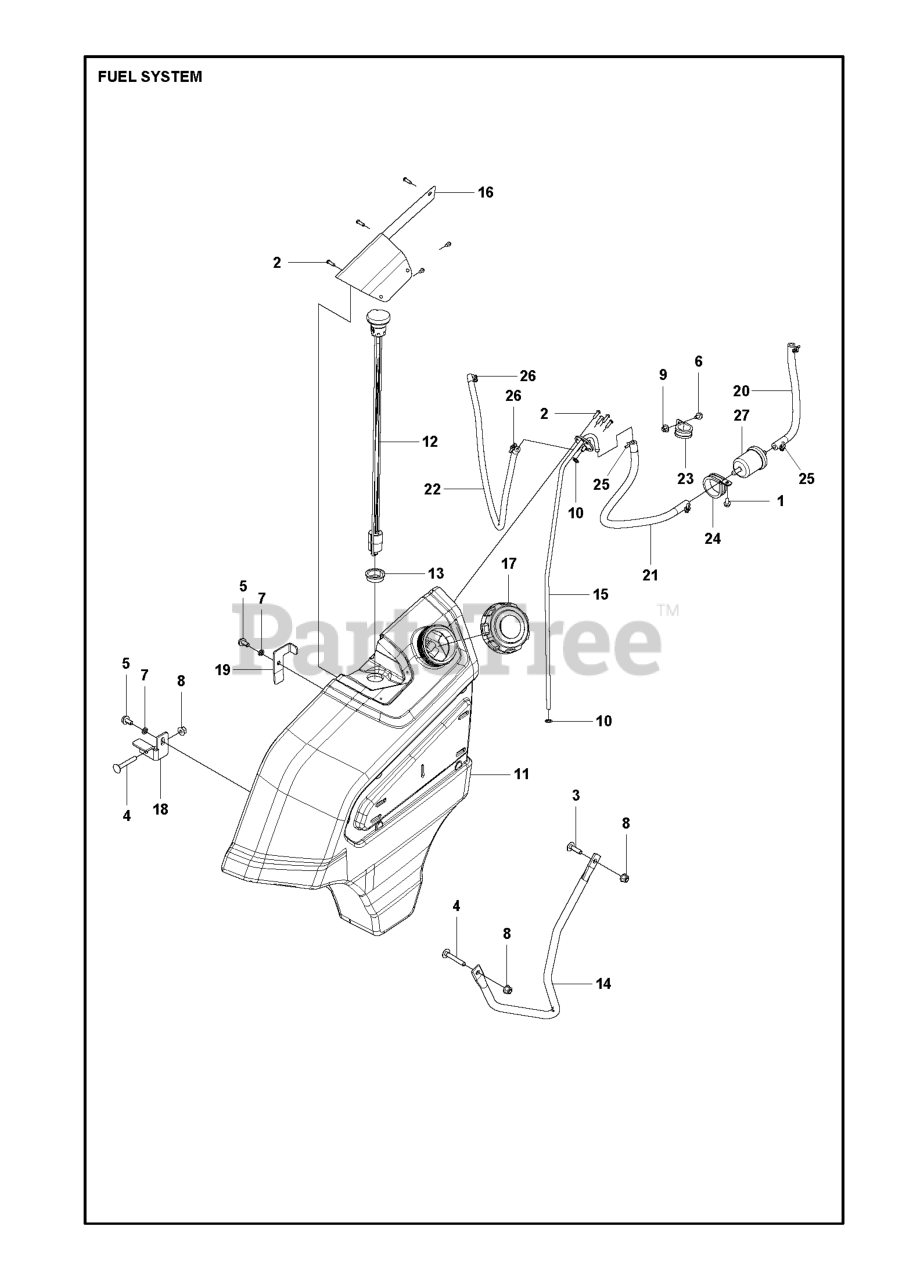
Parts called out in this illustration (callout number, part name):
1	SCREW EHHFM
2	SCREW ITXPANT T50X16 ZN/FE (A
7	WASHER LOCK 8.7X13.5X2.5 ZN FL
8	NUT FLANGE
9	NUT FLANGE
13	GROMMET, FUEL SENSOR
23	HOSE CLAMP
25	RP HOSE CLAMP FUEL HOSE
